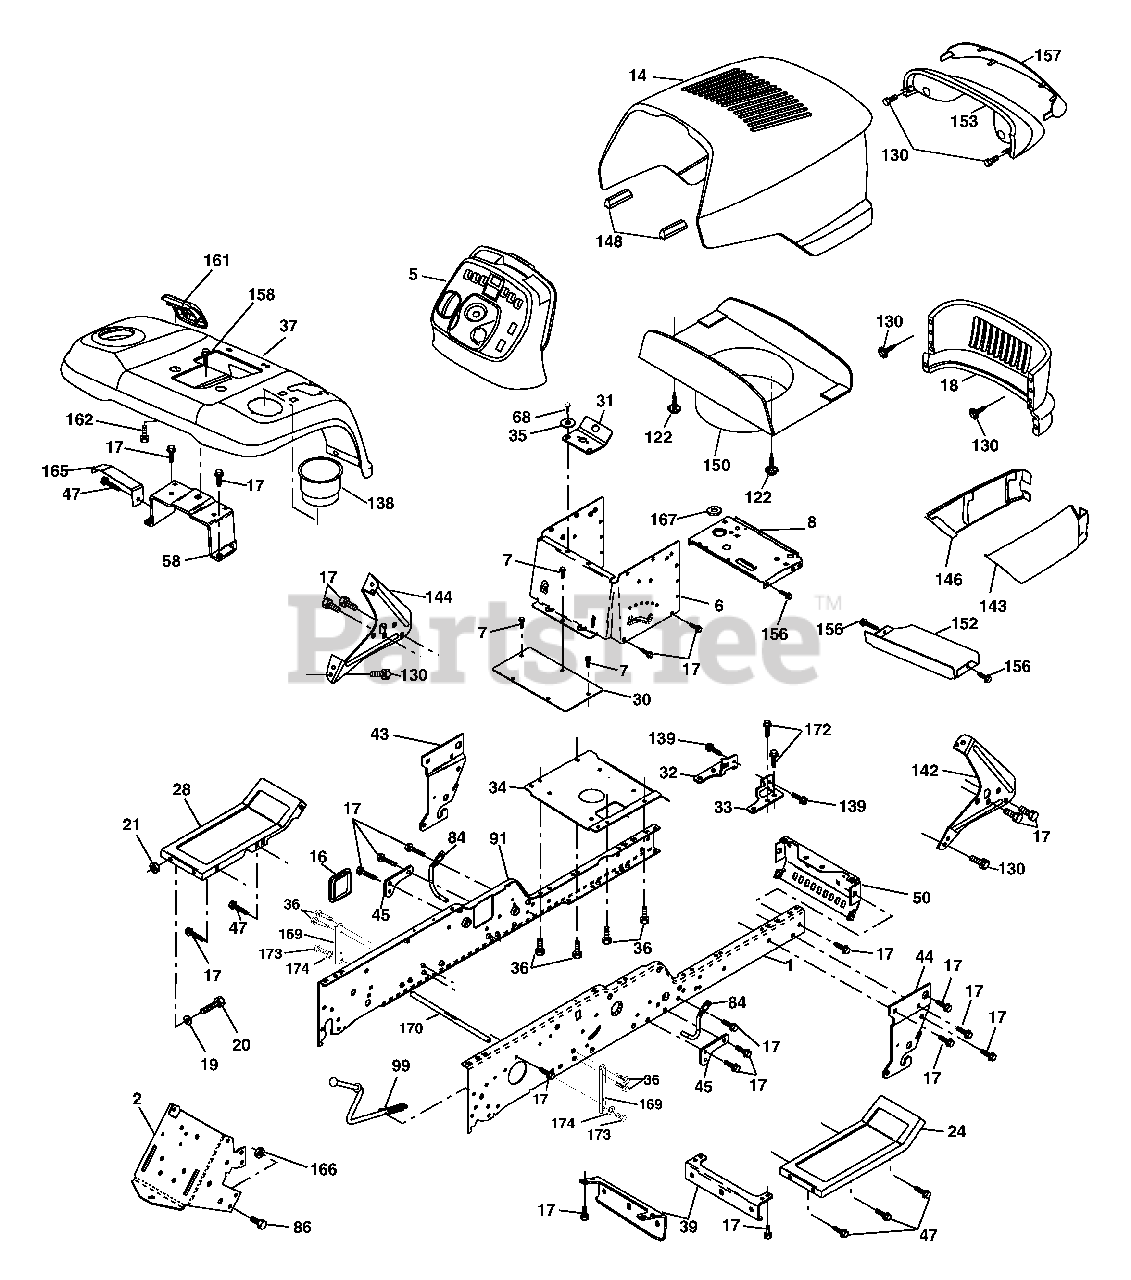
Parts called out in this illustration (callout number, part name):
1	Rail, Frame RH
2	Drawbar, Gt
5	Dash
6	Dash Asm., Lower
7	Screw, Thd Cut 1/4-20 x 1/2
8	Support, Battery
14	Hood Asm., Pnt
16	Cover, Access
17	Screw, 3/8-16 x 3/4
18	Grille
19	Washer
20	Bolt, Fin Hex 3/8-16 x 1
21	Nut, Lock Hex w/Ins. 3/8-16 unc
24	Footrest, RH
28	Footrest, LH
30	Saddle, Hydro 1995
31	Bracket, Supt 1-pc VGT Steering
32	Bracket, Pivot Chassis LH
33	Bracket, Pivot Chassis RH
34	Plate Asm. Engine Chassis
35	Washer 11/32 x 11/16 x 16 Ga.
36	Screw 5/16-18 x 3/4
37	Fender, Pnt.
39	Bracket, Axle Front
43	Bracket, Spnsn Front Lh
44	Bracket, Spnsn Front Rh
45	Bracket Arm Susp.
47	Screw Thdrol 3/8-16 x 1/2 TYT
50	Bracket, Chassis Front
58	Bracket Asm., Fender
68	Screw, Thd 5/16-18 x 1/2
84	Upstop
86	Bolt, Fin Hex 7/16-14 unc x 1
91	Rail, Frame Lh
99	Rod By Pass
122	Screw Hex Wshd 10-32 x 5/8
130	Screw 10 x 3/4 Single Lead Hex
138	Cupholder YTGT
139	Bolt Shoulder 5/16-18 TT
142	Bracket Dash RH
143	Skirt Grill RH
144	Bracket Dash LH
146	Skirt Grill LH
148	Extrusion Bumper
150	Duct Heat Hood
152	Shield Browning
153	Light Box Asm. w/Lens
156	Screw 5/16-18 x 3/4
157	Lens, Bar
158	Screw Thdrol 3/8-16 x 1/2
159	Screw 3/8-16 x 3/4
161	Console Fuel Window
162	Screw 1/4-1/2
165	Bracket Support Tank
166	Nut, Crownlock 7/16-14 unc
167	Bushing
169	Bracket Chassis Sway
170	Rod Bracket Sway Brace
172	Screw 3/8-16 x .875
173	Bolt Fin Hex 5/16-18 x 3/4
174	Washer Lock Hvy Hlcl Spr 5/16
